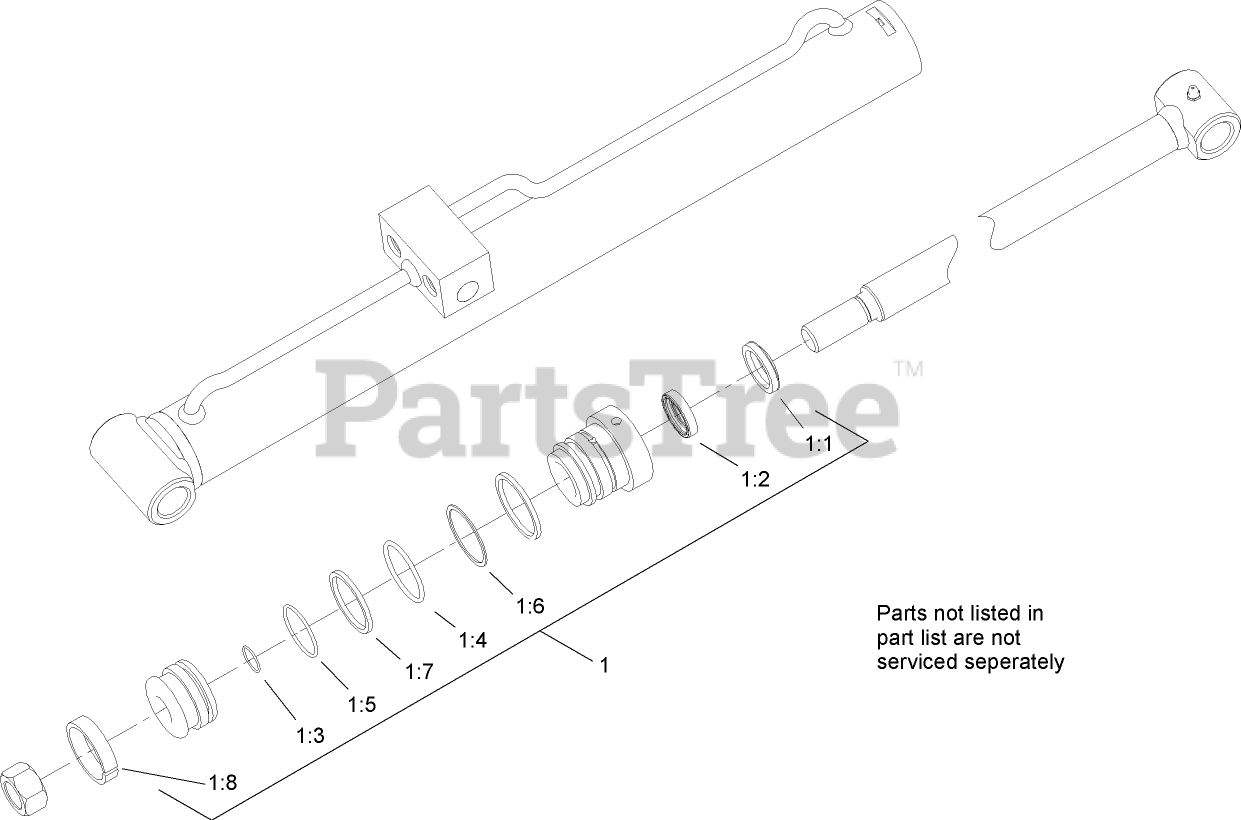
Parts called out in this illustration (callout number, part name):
1	SEAL KIT
1:1	Wiper
1:2	Seal
1:3	Seal-Dust
1:4	Seal-Dust
1:5	Seal-Dust
1:6	Back-up
1:7	Seal
1:8	WEAR RING
